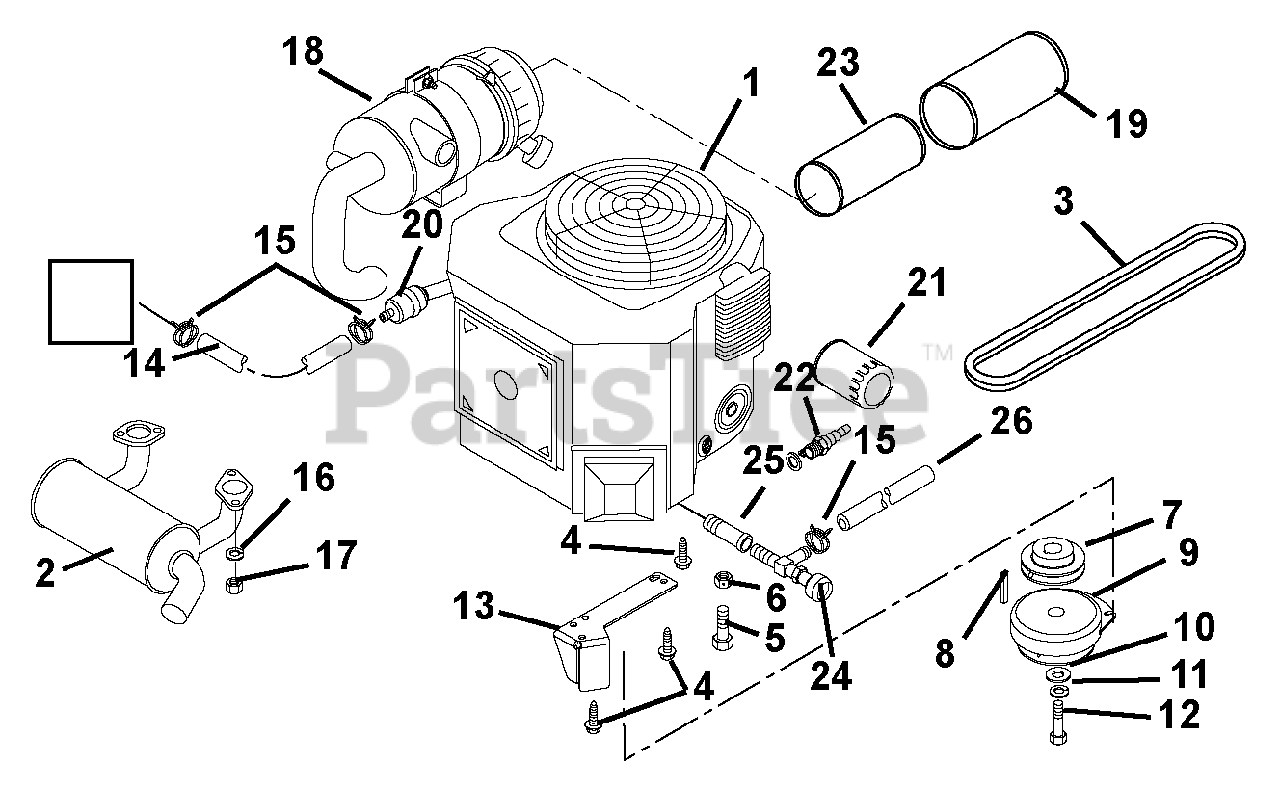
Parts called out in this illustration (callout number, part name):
1	ENGINE, KAWASAKI 21HP
2	MUFFLER, KAW (INTERMEDIATE-Z)
3	V-BELT, HA-RAW EDGE
4	@SCR-TAP .38-16X1.00 HWH TR YZ
5	@BLT-HEX .31-18X1.75 GR5 YWZC
6	@NUT-LK-TOP-FLG .31-18 YWZC
7	PLY-V 4.00 X 1.12 KEYWAY 1.54
8	KEY-SQ .25X.625X.25 SAE 8630
9	CLUTCH, ELE-W/HI TEMP GREASE
10	WSHR-FL-STL .515X1.625X.250 YZ
11	@WSHR-LK .44X.109 REG YWZC
12	BLT-HEX .44-20X2.50 GR5 YWZC
13	WMT, CLUTCH STOP
14	GAS LINE-BULK 1/4" I.D.
15	CLAMP-HOSE WIRE .490/.510X.116
16	@WSHR-LK .31X.078 REG YWZC
17	NUT-HEX M8-1.25 YWZC
18	AIR CLEANER ASSEMBLY
19	ELEMENT, OUTER PRIMARY
20	FILTER, FUEL - KOH CV20
21	FILTER,OIL - KAW
22	PLUG, SPARK
23	ELEMENT, INNER SAFETY
24	COCK, OIL DRAIN
25	ADAPTER, OIL DRAIN
26	GAS LINE-BULK 1/4" I.D.
NS	KIT,BRAKE POLE MODULE REPLACE
